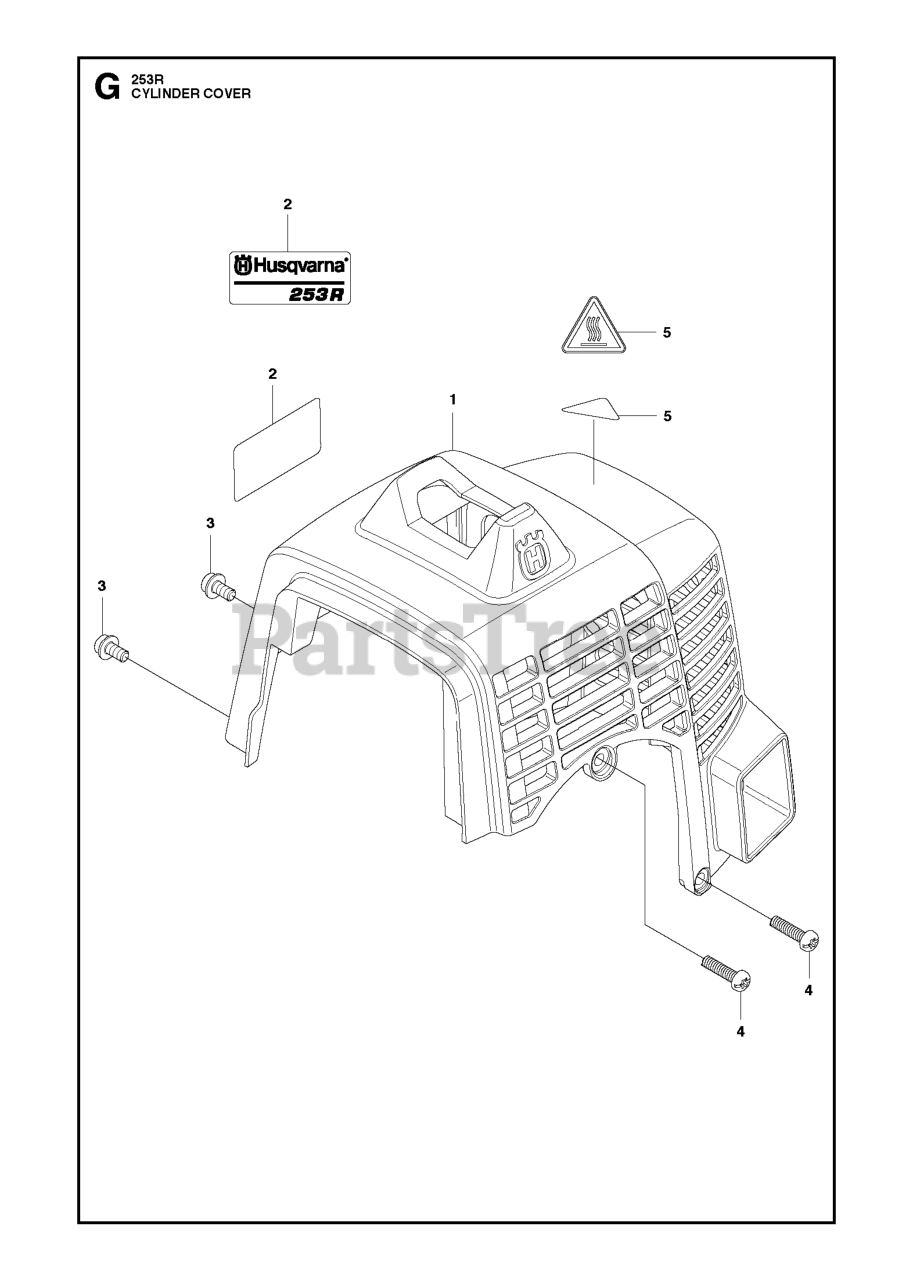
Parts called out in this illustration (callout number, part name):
3	BOLT (RPLS T495051010-11)
4	SCREW, TORX (RPLS T4970-52001)
5	LABEL HOT CAUTION
